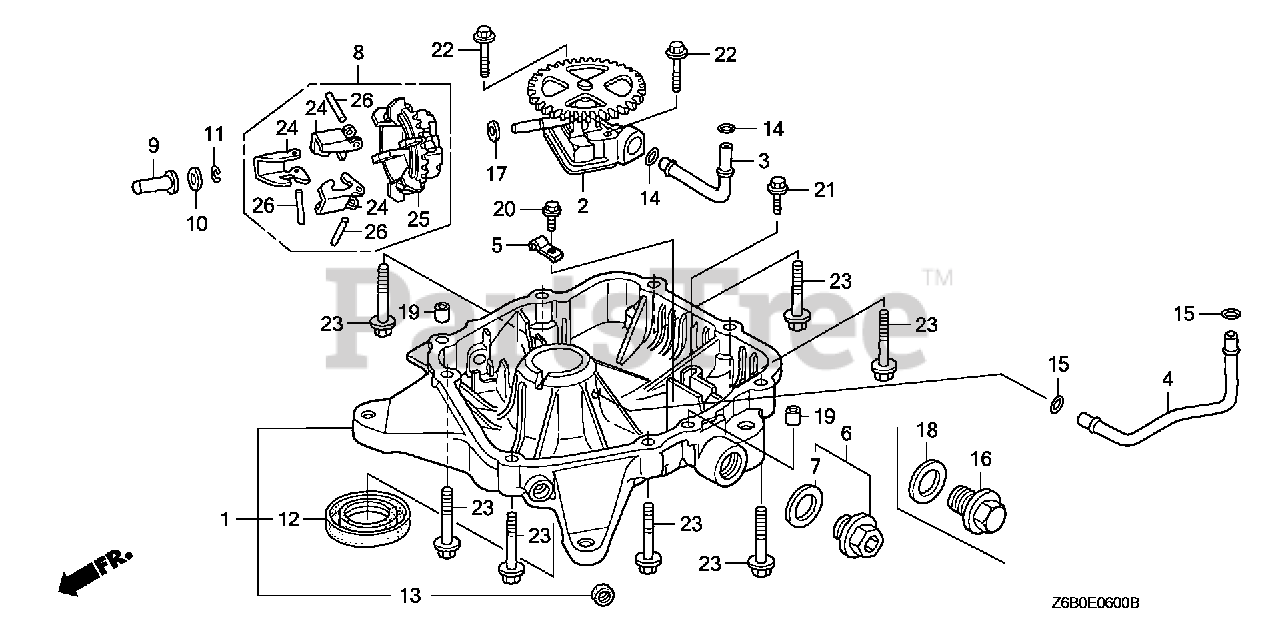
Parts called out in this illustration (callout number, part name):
1	PAN ASSY., OIL
2	PUMP ASSY., OIL
3	PIPE, OIL PUMP
4	PIPE, OIL SUPPLY
5	HOLDER, OIL PIPE
6	CAP ASSY., DRAIN
7	GASKET, OIL FILLER CAP
8	GOVERNOR ASSY.
9	SLIDER, GOVERNOR
10	WASHER (6X16)
11	CLIP, GOVERNOR HOLDER
12	OIL SEAL (31X50X8)
13	OIL SEAL (10X16X4.5)
14	O-RING (7.5X2.3)
15	O-RING (5.8X2)
17	WASHER, PLAIN (6MM)
19	PIN A, DOWEL (8X14)
20	BOLT, FLANGE (6X12) Use up to Engine SN 1543277.
22	BOLT, FLANGE (6X35)
23	BOLT, FLANGE (8X40) Use up to Engine SN 1003236.
24	WEIGHT, GOVERNOR
25	HOLDER, GOVERNOR WEIGHT
26	PIN, GOVERNOR WEIGHT
